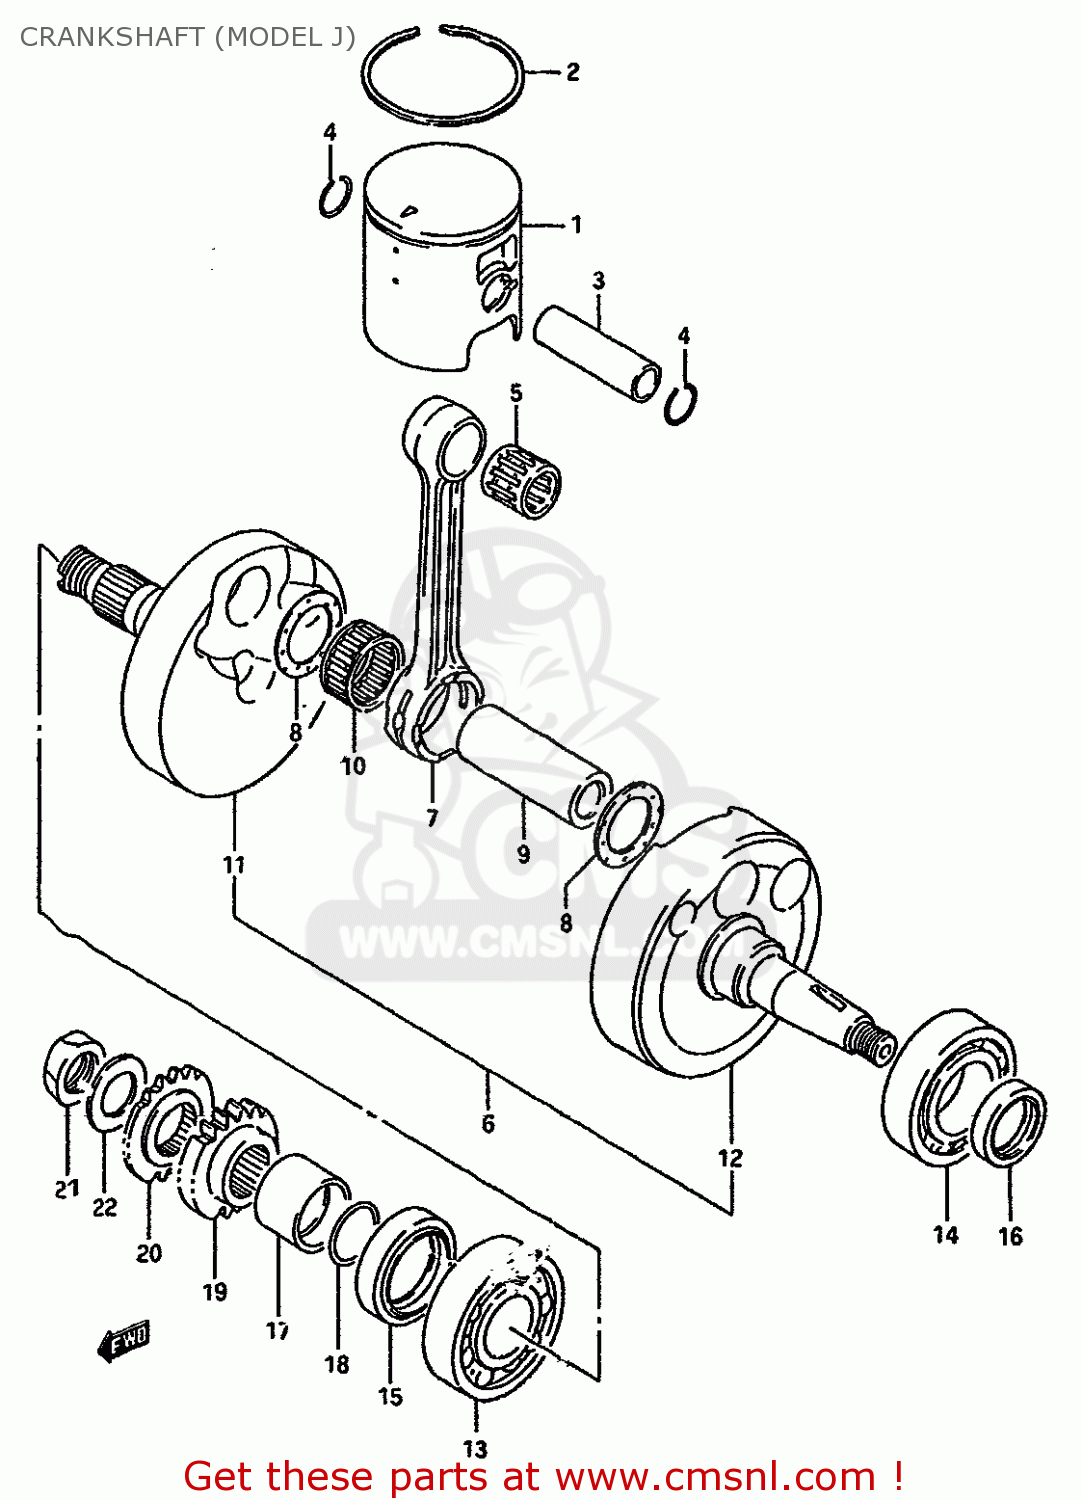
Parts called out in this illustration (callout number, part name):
1	PISTON SET
2	PISTON
3	RING,PISTON
4	PIN,PISTON
5	CIRCLIP
6	BEARING(15X19X20)
7	CRANKSHAFT ASSEMBLY
8	CONNECTING ROD
9	WASHER(22X35X1)
10	PIN,CRANK
11	BEARING(22X28X16)
12	CRANKSHAFT,RIGHT
13	CRANKSHAFT,LEFT
14	BEARING
15	BEARING(25X52X15)
16	SEAL,OIL(28X40X8)
17	SEAL,OIL(18X30X6)
18	SPACER,PRIMARY DRIVE GEAR
19	O RING(D:2.4,ID:19.8)
20	GEAR,PRIMARY DRIVEN
21	GEAR, GOVERNOR DRIVE (NT:19)
22	NUT
23	WASHER
